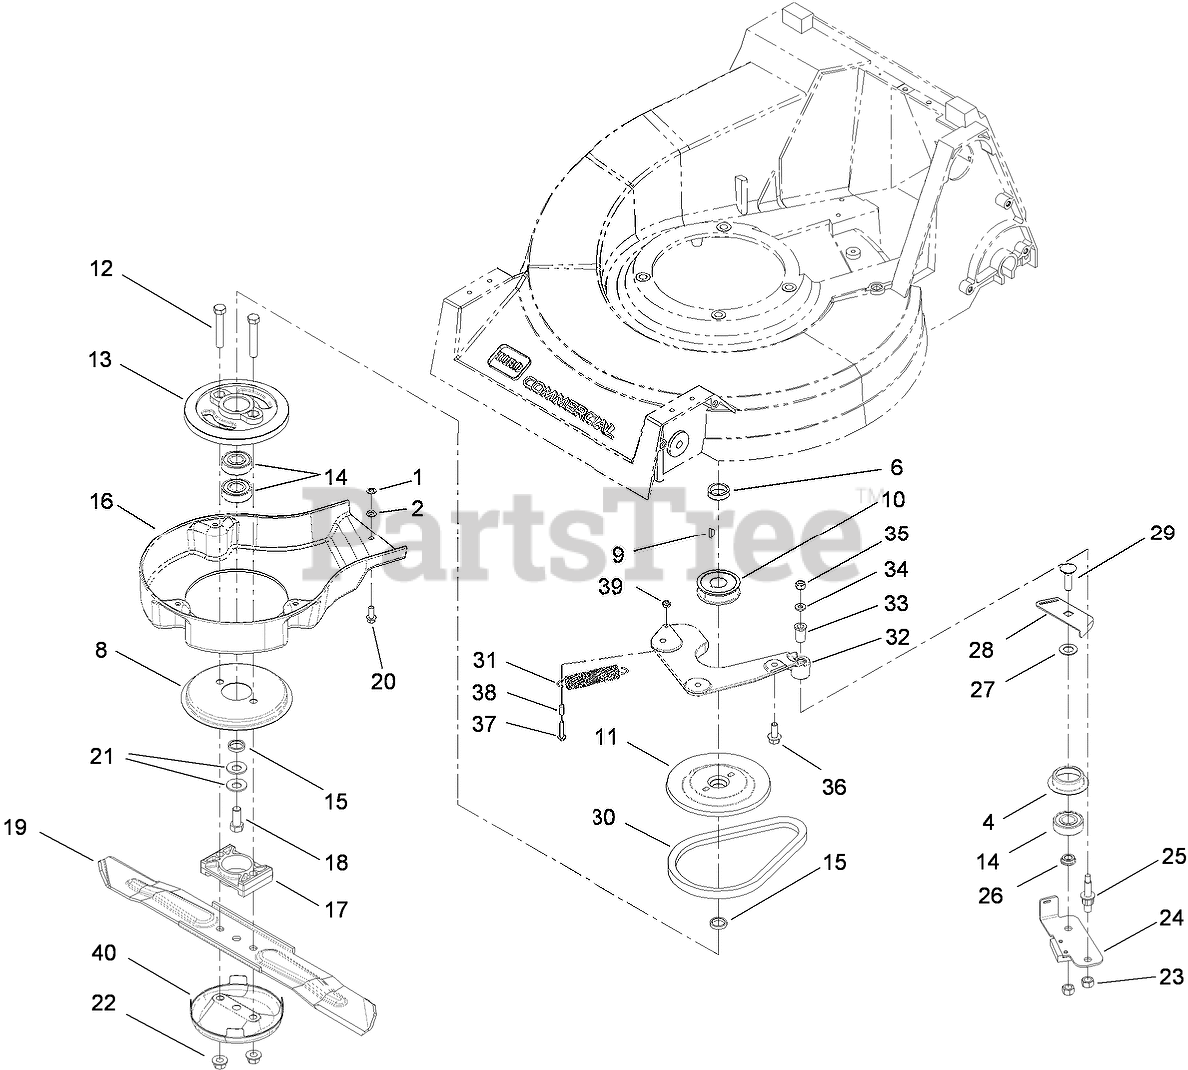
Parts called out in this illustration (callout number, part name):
1	NUT-RETAINER
2	WASHER-FLAT
4	RETAINER-BELT
6	SPACER-PULLEY
8	DISC
9	KEY-WOODRUFF
10	PULLEY-DRIVER
11	PULLEY-DRIVER, UPPER
12	SCREW-HH
13	DRUM
14	BEARING-BALL
15	SPACER-PLATE, BBC
16	SHIELD-BBC
17	SPACER-BLADE
18	SCREW-HH
19	BLADE-21 INCH
20	SCREW-HWH
21	WASHER-SPRING
22	NUT-LOCK
24	BRAKE ARM ASM
25	BOLT-SHOULDER
26	SPACER-BEARING
27	WASHER-PLAIN
28	PLATE-GUIDE
29	BOLT-CARR
30	BELT
31	SPRING-EXTENSION
32	PLATE-MOUNTING, BBC
33	BUSHING
34	WASHER-FLAT
35	NUT-LOCK, NI
36	SCREW-HHF
37	SCREW-TAP
38	SPACER-BBC
39	NUT-LOCK, NI
40	CUP-SCALP, ANTI
